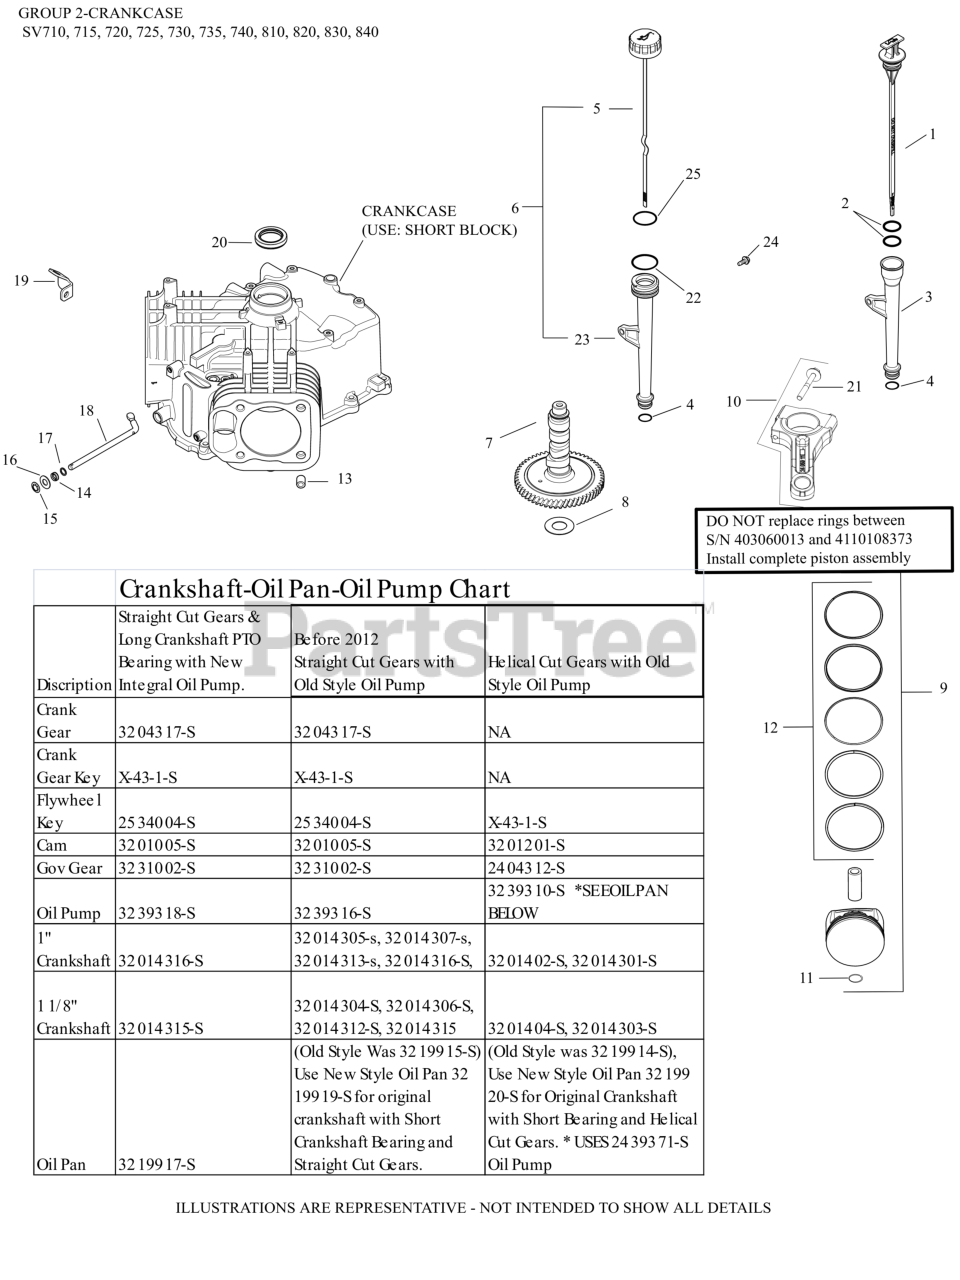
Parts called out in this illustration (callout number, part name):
1	DIPSTICK ASSEMBLY
3	TUBE ASSEMBLY-(#DSC)
4	O-RING, LOWER OIL FILL TUBE
5	RETAINER, BREATHER REED
6	REED, BREATHER
7	CAM ASSEMBLY
9	KIT, PISTON 725CC (STD) STYLE B
9	KIT, PISTON 725CC (.08) STYLE B
9	KIT, PISTON 725CC (.25) STYLE B
9	KIT, PISTON 725CC (.50) STYLE B
10	ROD, ASSY CON (STD)-USE 24 067 30-S
10	ROD, ASSY CON(.25mm) -USE 24 067 31-S
11	RETAINER, PISTON PIN
12	RING SET(STD)STYLE B-1.2mm Tp RING THICK
12	RING SET(.08)STYLE B-1.2mm RING THICK
12	RING SET(.25)STYLE B-1.2mm Tp RING THICK
12	RING SET(.50)STYLE B-1.2mm Tp RING THICK
13	PIN, LOCATING
14	SEAL, GOVERNOR CROSS SHAFT
15	RETAINER, RING
16	WASHER, FLAT 9 MM
17	WASHER, FLAT 11/32"
18	SHAFT, GOVERNOR CROSS
19	BRACKET, OIL FILL TUBE
20	SEAL, OIL (HELIX LIP)
21	KIT, ROD BOLTS-(#25086677S)
21	KIT, ROD BOLTS
24	SCREW, FLG THD FRM M5X0.8X13
